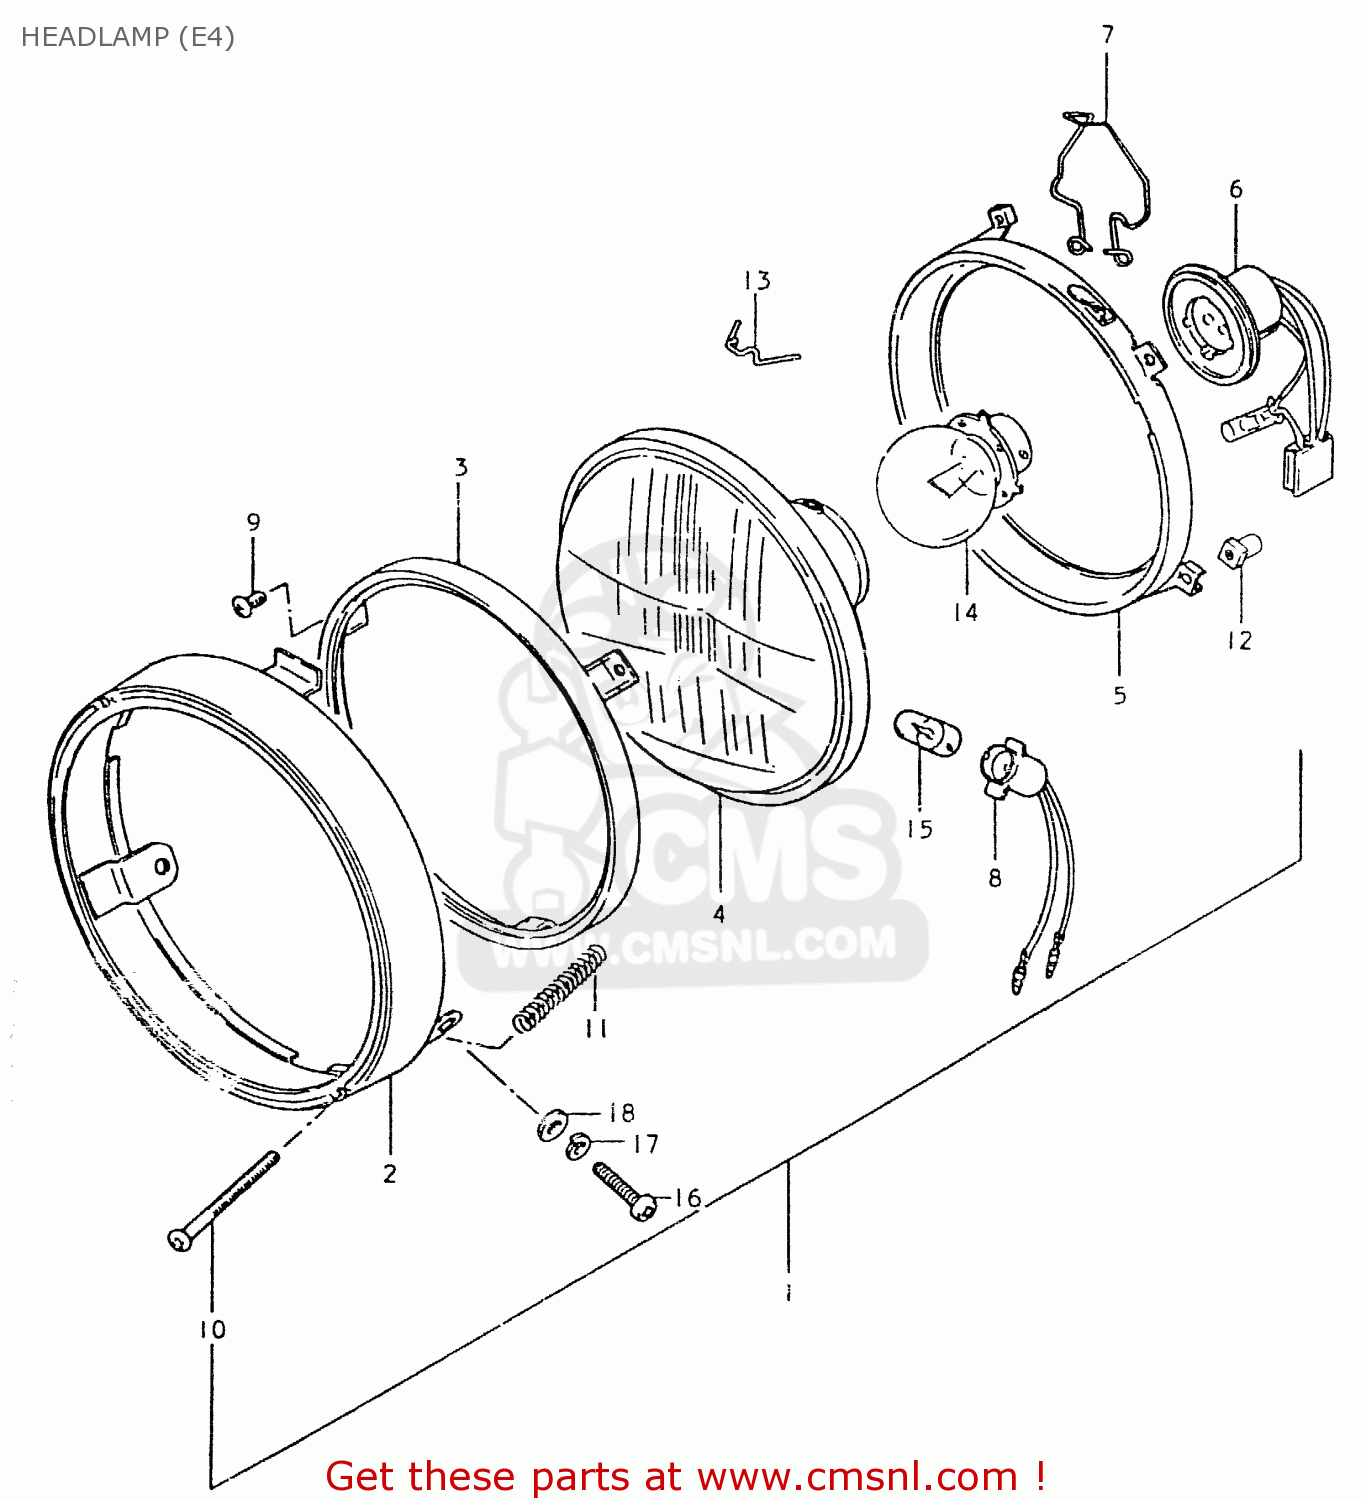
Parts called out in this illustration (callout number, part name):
1	HEADLAMP ASSY
2	RIM
3	RETAINER,HEADLAMP
4	UNIT
5	RING, MOUNTING
6	SOCKET
7	CLAMP,HEADLAMP
8	SOCKET
9	SCREW
10	SCREW,HEADLAMP ADJUST
11	SPRING,ADJUSTING
12	NUT,HEADLAMP ADJUSTER
13	SPRING,HEADLAMP UNIT
14	BULB (6V,25/25W)
15	BULB(6V4W,STANLEY,A1364J)
16	SCREW
17	LOCK WASHER
18	WASHER
